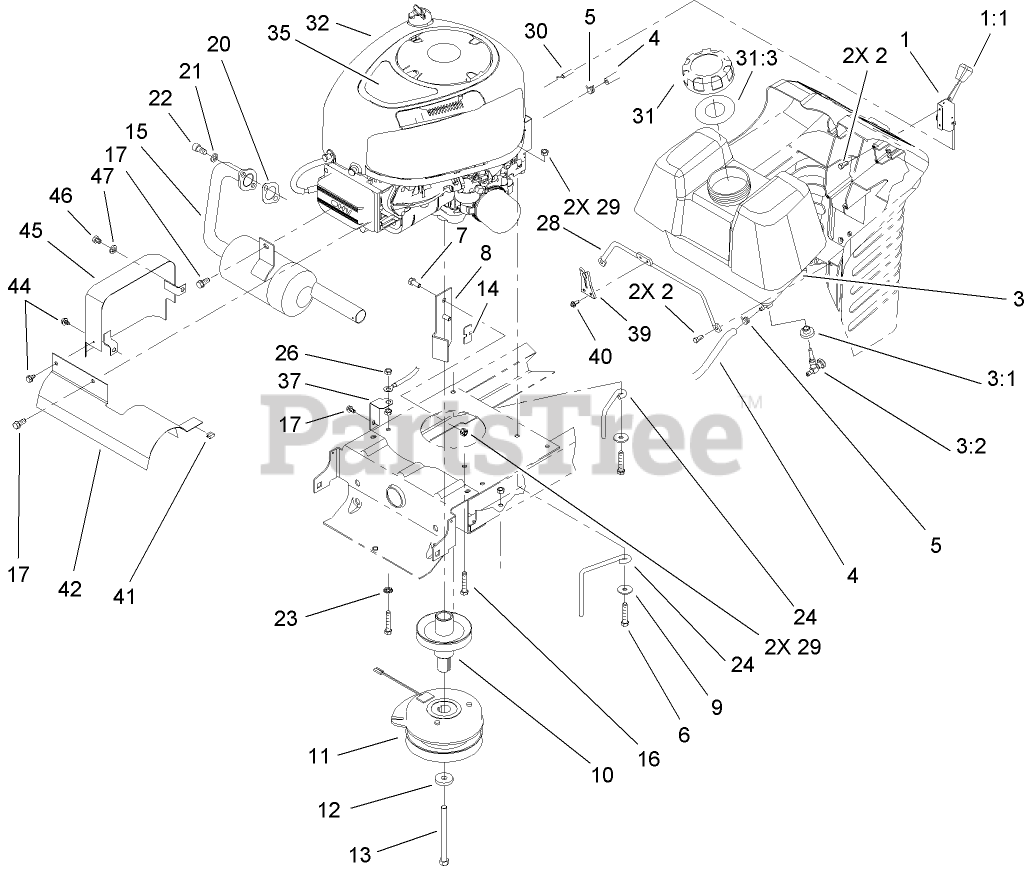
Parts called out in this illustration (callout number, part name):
1	THROTTLE CONTROL ASM
2	SCREW-SPECIAL
3	GAS TANK ASM
3:1	BUSHING
3:2	VALVE-FUEL
5	CLAMP-HOSE
6	SCREW-HH
7	SCREW-HH
8	STOP-CLUTCH
9	WASHER-PIVOT
10	PULLEY-ENGINE
11	CLUTCH-PTO, ELECTRIC
12	WASHER
13	SCREW-HH
14	BUMPER
15	MUFFLER-EXHAUST
16	SCREW-HWH, TAPTITE
17	SCREW-HWH
20	GASKET-EXHAUST
21	WASHER-LOCK
22	SCREW-HSH
23	WASHER-LOCK
24	GUIDE-BELT, RH
26	NUT-KEPS
28	ROD-TANK, GAS
29	NUT-LOCK, NI
30	THROTTLE CABLE ASM
31	GAS CAP ASM
31:3	GASKET-CAP, GAS
32	Loose Parts Package
35	DECAL-ENGINE
37	BRACKET-GROUND
39	LATCH-HOOD
40	SCREW-HWH
41	CLIP-TINNERMAN
42	SHIELD-MUFFLER
44	SCREW-HWHTF
45	HEAT SHIELD ASM
46	SCREW-HH
47	WASHER-LOCK
